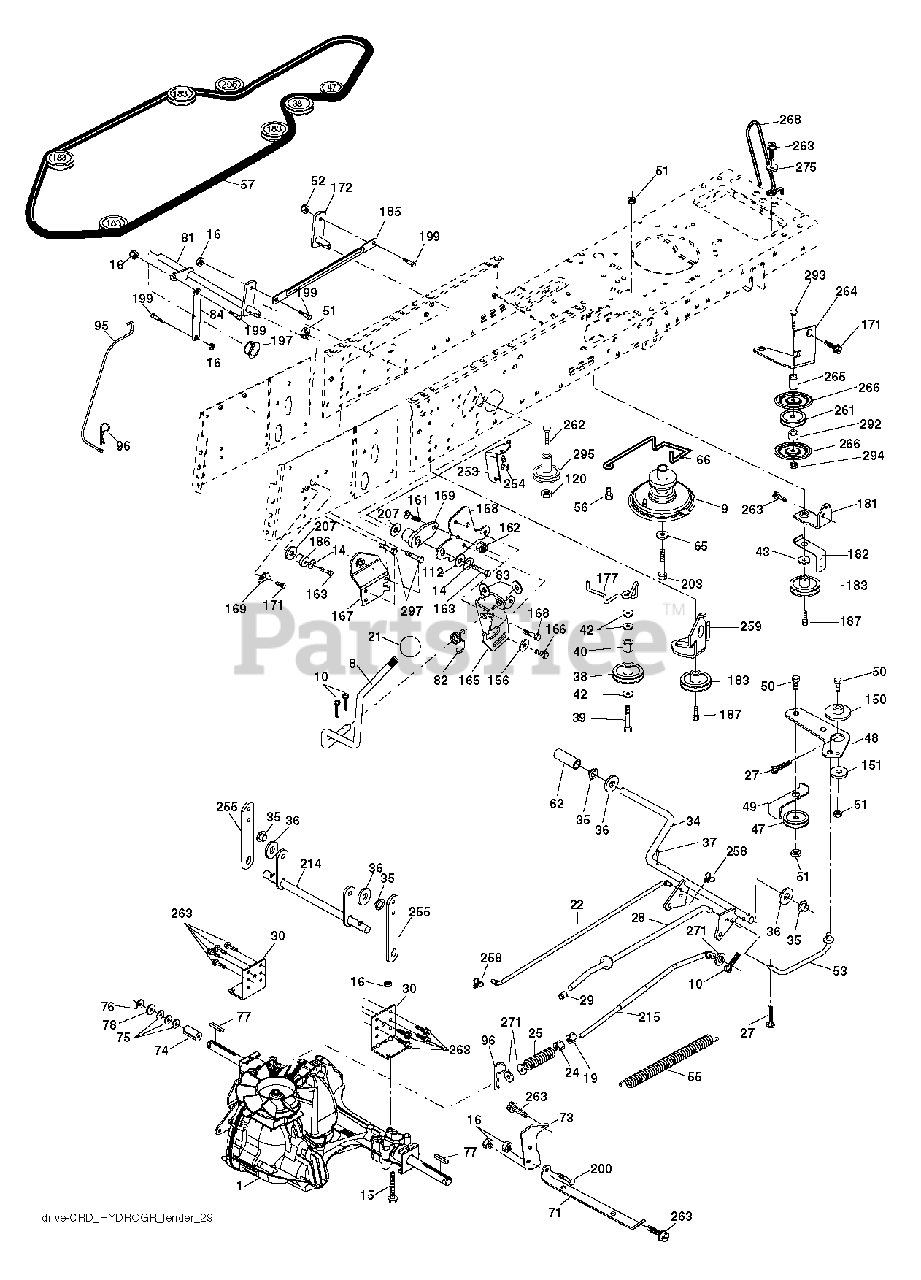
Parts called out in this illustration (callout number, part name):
8	ROD SHIFT FENDER ADJUST LT
10	PIN COTTER
14	LOCKWASHER
15	BOLT HEX 5/16-18 GR 5
16	NUT.71038.31-18.HEX.NYLOCK
19	NUT
21	KNOB T (1/2-HOLE)
24	NUT
27	COTTER PIN
28	ROD, PARKING BRAKE
29	PLUNGER CAP
30	BRKT, TRNSXLE MNT 20"
34	SHAFT, FOOT PEDAL
35	BEARING.NYLON
36	WASHER LT
37	DRIVE PIN
38	PULLEY.FLAT
42	WASHER
47	IDLER PULLEY
48	BELLCRANK, CLUTCH
49	RETAIN BELT
50	BOLT.3/8-16X1.50
51	LOCKNUT
52	LOCKNUT
53	LINK.CLUTCH.7.66.2005
55	SPRING, RETURN LT
56	SCREW.3/8-16
62	PEDAL COVER T
65	LOCKWASHER
66	KEEPER BELT ENGINE
71	STRAP TORQUE LH HYDRO
73	STRAP TORQUE RH HYDRO
74	SPACER AXLE
76	E-RING LT
77	SQUARE KEY
81	SHAFT ASSY
82	SHIFT SPRING
83	WASHER
96	RETAINER M
112	WASHER LT
120	NUT LOCK FLG 3/8-16 UNC
150	BUSHING.BELLCRANK.GRD.DR
151	WASHER 12/32X2X10GA
156	WASHER.SRRTD.5/16
158	BRACKET.SHIFT.MOUNT
159	HUB.SHIFT
161	BOLT
162	NUT.CROWNLOCK.1/4
165	BRACKET.PIVOT.LEVER
167	BRACKET
168	BOLT.SHOULDER.5/16-18X
169	PLATE.FASTENING.CROSS.SHAFT
183	PULLEY.V-IDLER.
187	BOLT.5/16-18X1.25
197	NYLINER SNAP 5/8" ID
199	BOLT SHOULDER 5/16-18 UNC
200	BOLT
207	WASHER NYL
254	SCREW 3/8-16X1
258	CLIP RETAINER
261	FLAT IDLER PULLEY
263	SCREW, 3/8-16X3/4
271	WASHER
275	WASHER
294	NUT, HEX 3/8-16
295	PULLEY IDLER COMPOSITE
297	SCREW LT.3/8-46X5/8
